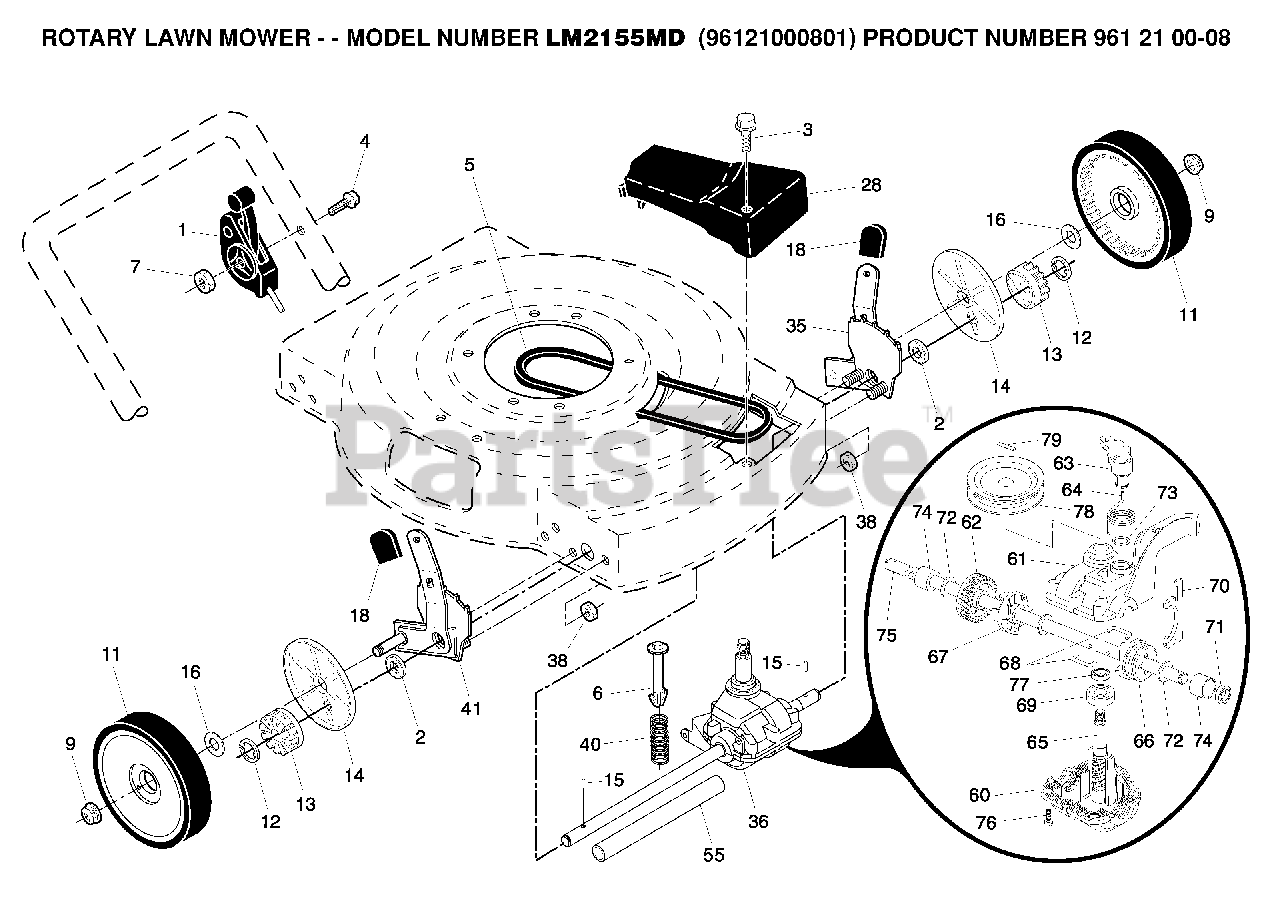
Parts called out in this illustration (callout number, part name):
1	DRIVE CONTROL 59.8 FWGD
2	BEARING
5	BELT THERM .32
6	SPRING RETAINER
7	NUT.HEX.FLANGE.1/4
9	HEX FLANGE LOCKNT
12	E-RING 7/16 RE
13	PINION
14	COVER.DUST.WHEEL
15	PAWL.DRIVE
16	WASHER FLUT
18	SELECTOR KNOB
36	TRANSMISSION.22.FGD.W/PULLEY
38	LOCKNUT
40	SPRING.EXTENSION
55	DRV SHAFT TUBE PM
60	LOWER CASE
61	UPPER CASE
62	GEAR.27.TEETH.WALK.MOWER
63	LEVER, CLUTCH
64	SPRING, RETURN
65	SHAFT, INPUT
66	DOG, MOVABLE
67	DOG, FIXED
68	WIRE, FORMED
70	FORK, SHIFT
71	SEAL.OUTPUT.SHAFT
73	SEAL, CASE
75	SHAFT OUTPUT
77	SEAL INPUT SHAFT
78	PULLEY.DRIVEN.FGD
79	PIN RETAINER
